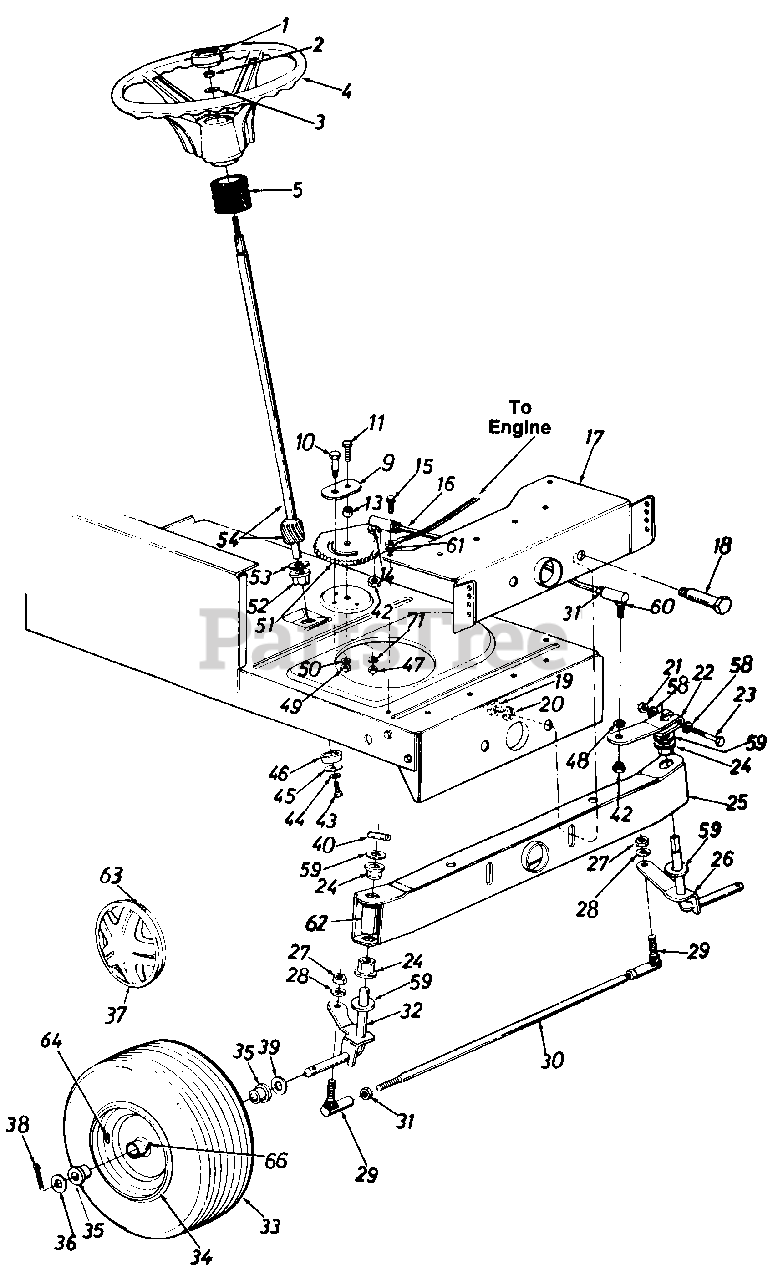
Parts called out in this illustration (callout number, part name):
1	Steering Wheel Cap
2	Hex L-Nut 5/16-24 Thd.
3	Belleville Wash. 345n l.D.
4	Steering Wheel
5	Steering Bellow-9"
9	Retainer Plate
10	Shoulder Bolt .437" Dia. x .35 Lg. 5/16-18 Thd.
11	Hex Bolt 3/8-24 x 1.0" Lg. (Grade 5)
13	Spacer .380" I.D. x .625" O.D. x .227
14	L-Wash. 3/8" I.D.*
15	Hex Wash. Hd. Self-Tap Scr.
16	Steering Drag Link
17	Front Pivot Brkt.
18	Shoulder Bolt .498n Dia. x 2.04 Lg. 3/8-16 Thd.
19	Hex Nut 3/8-16 Thd.*
20	L-Wash. 3/8n l.D.*
21	Hex Cent. L-Nut 5/16-24 0 Thd.
22	Steering Arm Front Axle
23	Hex Bolt 5/16-24 x 2.00" Lg. (Grade 5)
24	Hex Flg. Brg. .634 I.D.
26	Front Axle Ass'y.-L.H.
27	Hex Nut 3/8-24 Thd.*
28	L-Wash. 3/8" l.D.*
29	Ball Joint 3/8-24 Thd.
31	Hex Jam Nut 3/8-24 Thd.*
32	Front Axle Ass'y.-R.H.
33	Wheel Ass'y. Comp.
34	Front Wheel Rim Only
35	Bronze Bearing
36	Fl-Wash. .635 I.D. x 1.59" O.D.
37	Spoked Hub Cap
38	Cotter Pin 1/8" Dia. x 1.25"
39	Fl-Wash. .640" I.D. x 1.24" O.D.
40	Spring Roll Pin
42	Hex Jam Nut 3/8-24 Thd.
43	Hex L-Bolt 5/16-18 x .62"
44	L-Wash. 5/16" I.D.
45	Fl-Wash. .33" l.D. x 1.25" O.D.
46	Spacer (Plastic)
47	Hex Nut 3/8-24 Thd.
48	L-Wash. 318" I.D.
49	Hex Nut 5/16-18 Thd .
50	L-Wash. 5/16" l.D.
51	Steering Gear Segment
52	Hex Flg. Brg. .634 I.D.
53	Fl-Wash. (Hardened)
54	Steering Shaft
58	Wave-) Wash 82n 1 D x 62n O.D.
59	Fl-Wash. (Hardened)
60	Drag Link Ball Joint 3/8-24 0 Thd.
61	Ext. L-Wash. 5/16" l.D.
62	Plastic Tube
63	Spring Clip
64	Bell-Wash. 39" l.D. x 1.38" O.D.
